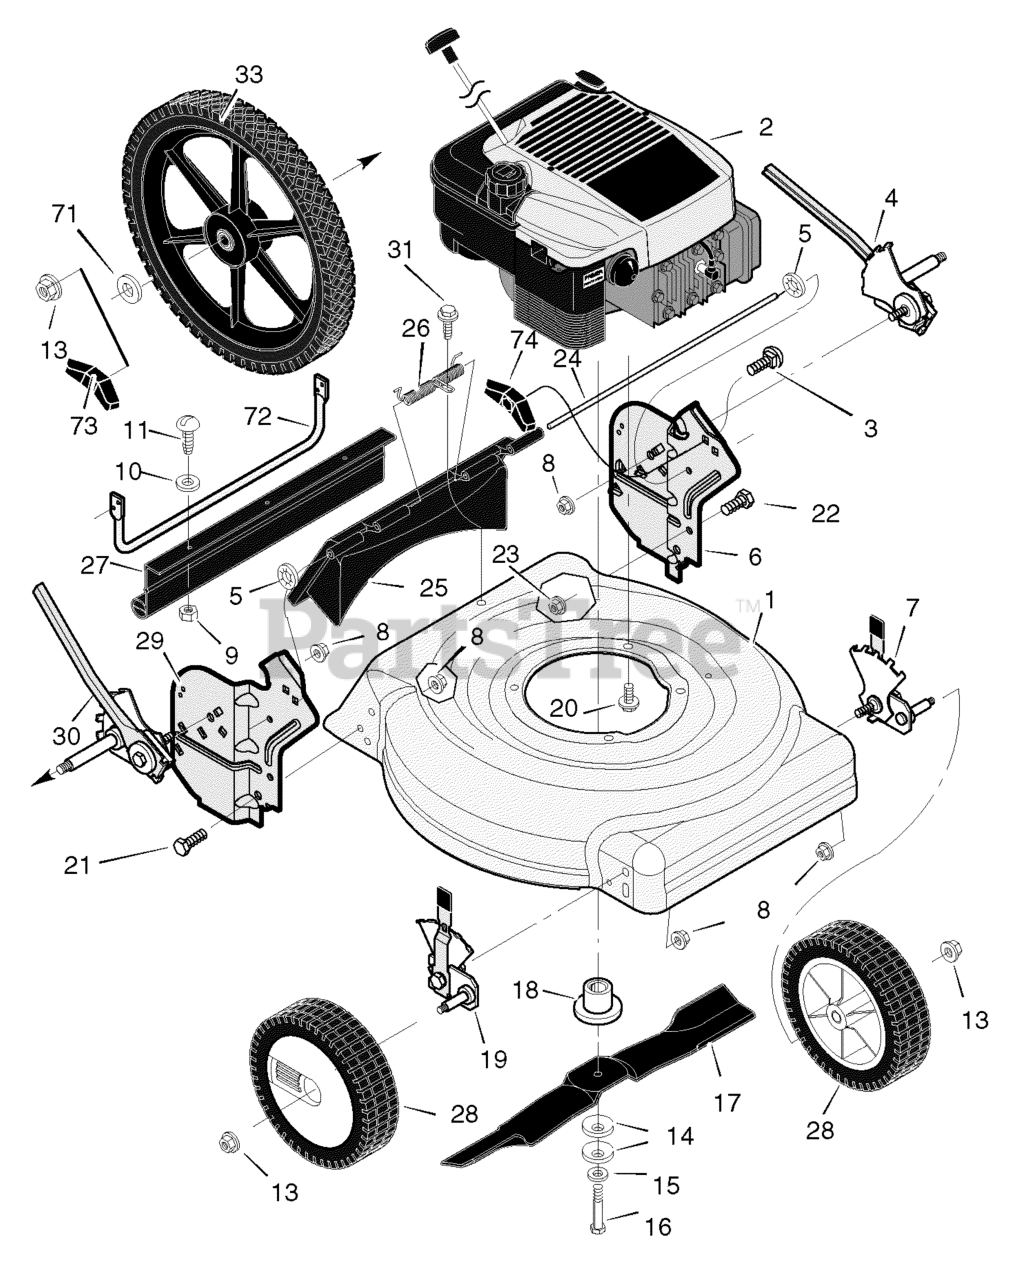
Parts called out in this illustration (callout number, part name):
1	Housing
2	Engine *
3	Bolt, Carriage
4	Adjuster, Left Rear Height
5	Retainer, Push
6	Bracket, Left Handle
7	Adjuster, Left Front Height
8	Nut, Flange
9	Nut, Hex
10	Washer
11	Screw
13	Nut, Flange
14	Washer, Belleville
15	Washer
18	Adapter, Blade
19	Adjuster, Right Front Height
20	Bolt, Engine
21	Bolt
22	Bolt
23	Nut, Flange
24	Rod, Pivot
25	Door, Rear (Black)
25	Door, Rear (Gray)
26	Spring
27	Guard, Rear
28	Wheel & Tire *
29	Bracket, Right Handle
30	Adjuster, Right Rear Height
33	Wheel, Rear *
